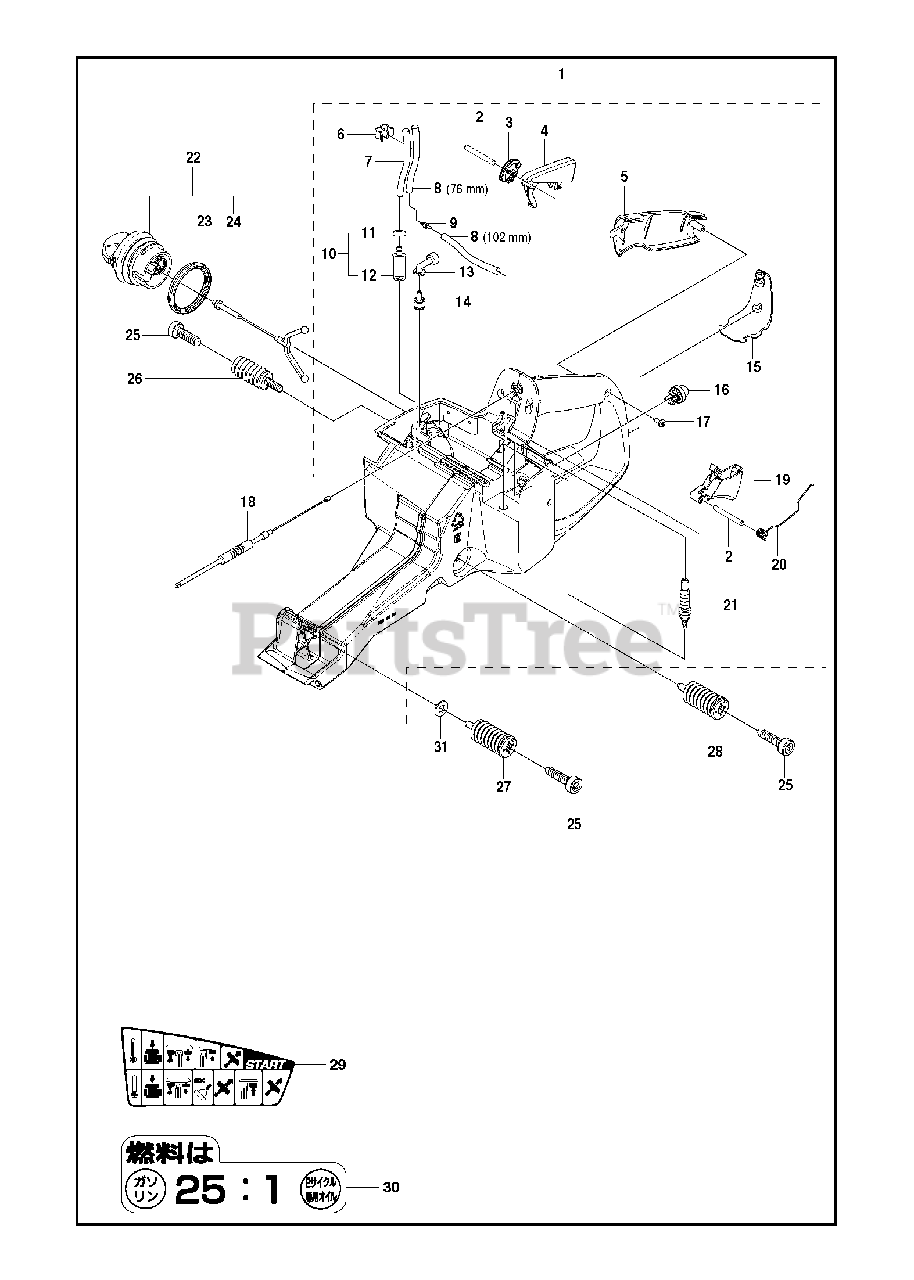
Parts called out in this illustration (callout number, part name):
1	FUEL TANK ASSY
2	PARALLEL PIN
4	THROTTLE LOCKOUT
7	FUEL HOSE
8	FUEL HOSE
13	TANK VENT ASSY
14	TANK VENT ASSY
15	GROUND SUPPORT
17	SCREW CITXPANT
18	THROTTLE CABLE ASSY
19	THROTTLE CONTROL
22	TANK CAP ASSY
25	SCREW ITXSCM
26	ANTIVIBRATION ELEMENT
27	ANTIVIBRATION ELEMENT
28	ANTIVIBRATION ELEMENT
